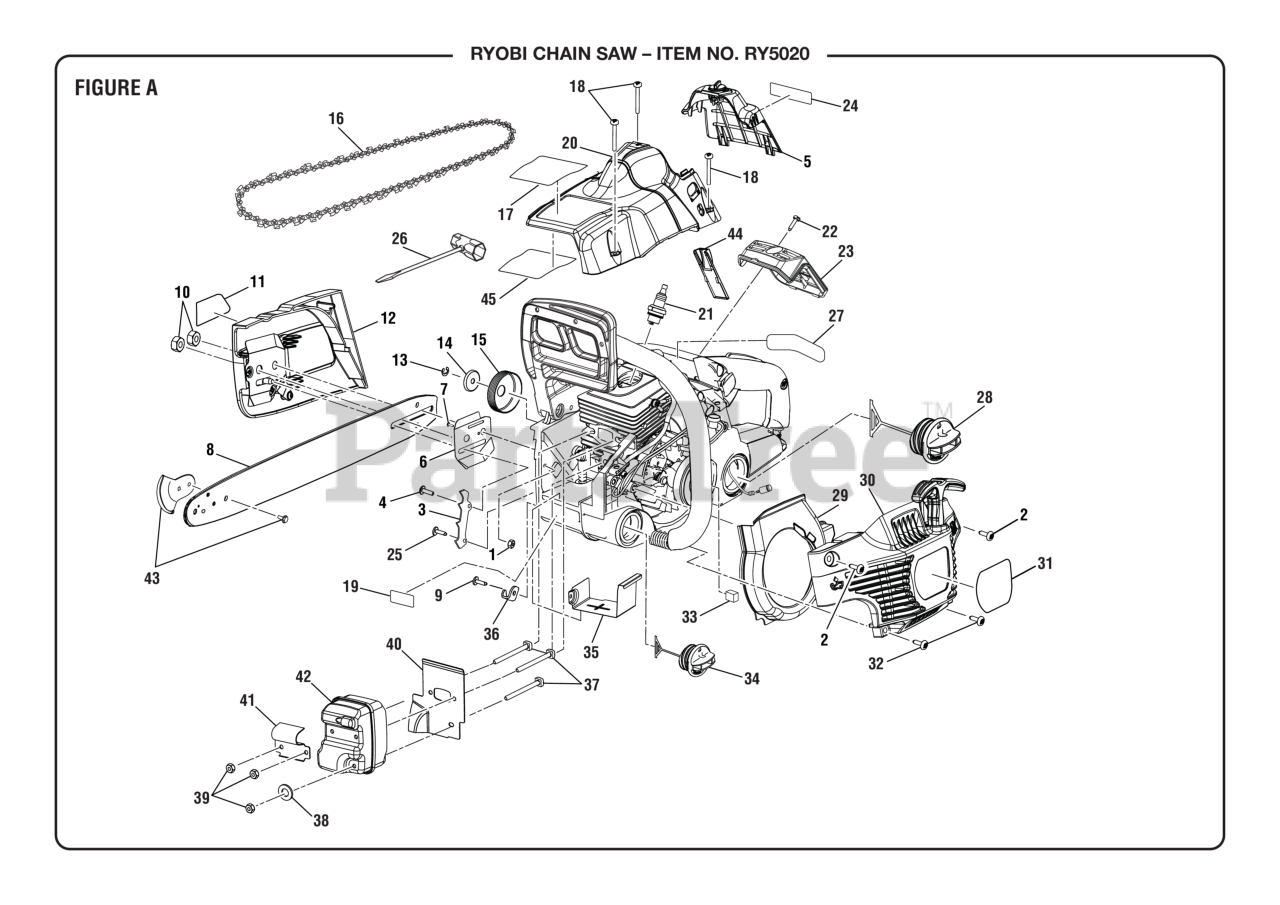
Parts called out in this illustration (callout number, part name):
1	LOCK NUT, HEX (10-24)
2	Screw, Truss Hd., Plastite (10-14 x 5/8")
3	BUMPER SPIKE
4	Screw (10-24 x 5/8 in., Torx Pan Hd.)
5	Filter Cover
6	Inner Guide Plate
7	Screw (#6-19 x 1/2 in., Phillips Hd. T.F.)
8	20 in. Guide Bar w/SAFE-T-TIP
9	Screw (10-14 x 1/2 in., Torx Truss Hd. T.F.)
10	Hex Nut (5/16-18 Flange)
11	Logo Label
12	Chain Cover Assembly
13	RING, RETAINING
14	Cupped Washer
15	Sprocket Drum and Bearing Assembly (.325 chain)
16	Chain (.325 x 78 links, 20 in.)
17	Warning Label
18	Screw (10-16 x 1-1/2 in. Special)
19	Warning Label (Combustion)
20	Cylinder Housing
21	SPARK PLUG CHAMPION - RCJ-6Y
22	Screw-Slotted Pan Hd. (8-16 x 5/8")
23	Air Filter 50cc
24	Chain Replacement Label
25	Vacuum Tube Screw (10-14 x 1/2 in., T25 Torx Truss Hd. T.F.)
26	Combination Wrench
27	Starting Instruction Label
28	Fuel Cap Assembly
29	Fan Housing Baffle
30	Starter Cover Assembly
31	Logo Label (Item No. RY5020)
32	Screw, Truss Hd., Plastite (10-14 x 7/8")
33	PRE FILTER
34	Oil Cap Assembly
35	Heat Shield
36	Chain Catcher
37	Muffler Bolt (Square Hd.)
38	Washer (OD16 x ID5.5 x 1.5t)
39	NUT-LOCKING HEX (10-32)
40	Muffler Gasket
41	Muffler Deflector
42	Muffler Assembly
43	SAFE-T-TIP and Screw Assembly (.325 Bar)
44	Cylinder Housing Divider
45	Heat Reflector Tape
